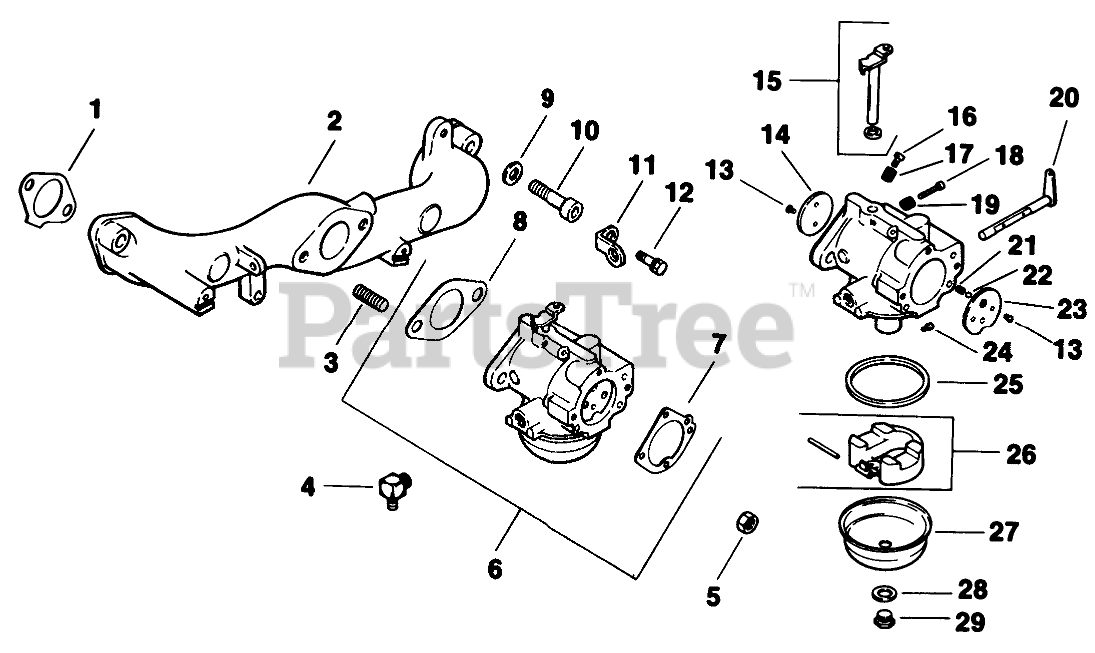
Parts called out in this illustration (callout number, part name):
1	Gasket-Intake
2	Manifold-Intake
3	Stud
4	Connector-90deg.
5	Nut
6	Carburetor Kit w/Linkage (Incl. Ref. #7-9,14-30)
7	Gasket
8	Carburetor Assembly Ref.
9	Gasket
10	Screw
11	Screw
12	Strap Lifting
13	Screw
14	Screw-Throttle Plate
15	Plate-Throttle
16	Shaft Assembly
17	Valve-Needle
18	Spring
19	Screw
20	Spring
21	Lever-Choke
22	Spring-Choke
23	Ball-Choke
24	Plate-Choke
25	Jet-Main
26	Bowl-Gasket
27	Kit-Float
28	Bowl
29	Screw-Bowl
30	Gasket-Bowl
